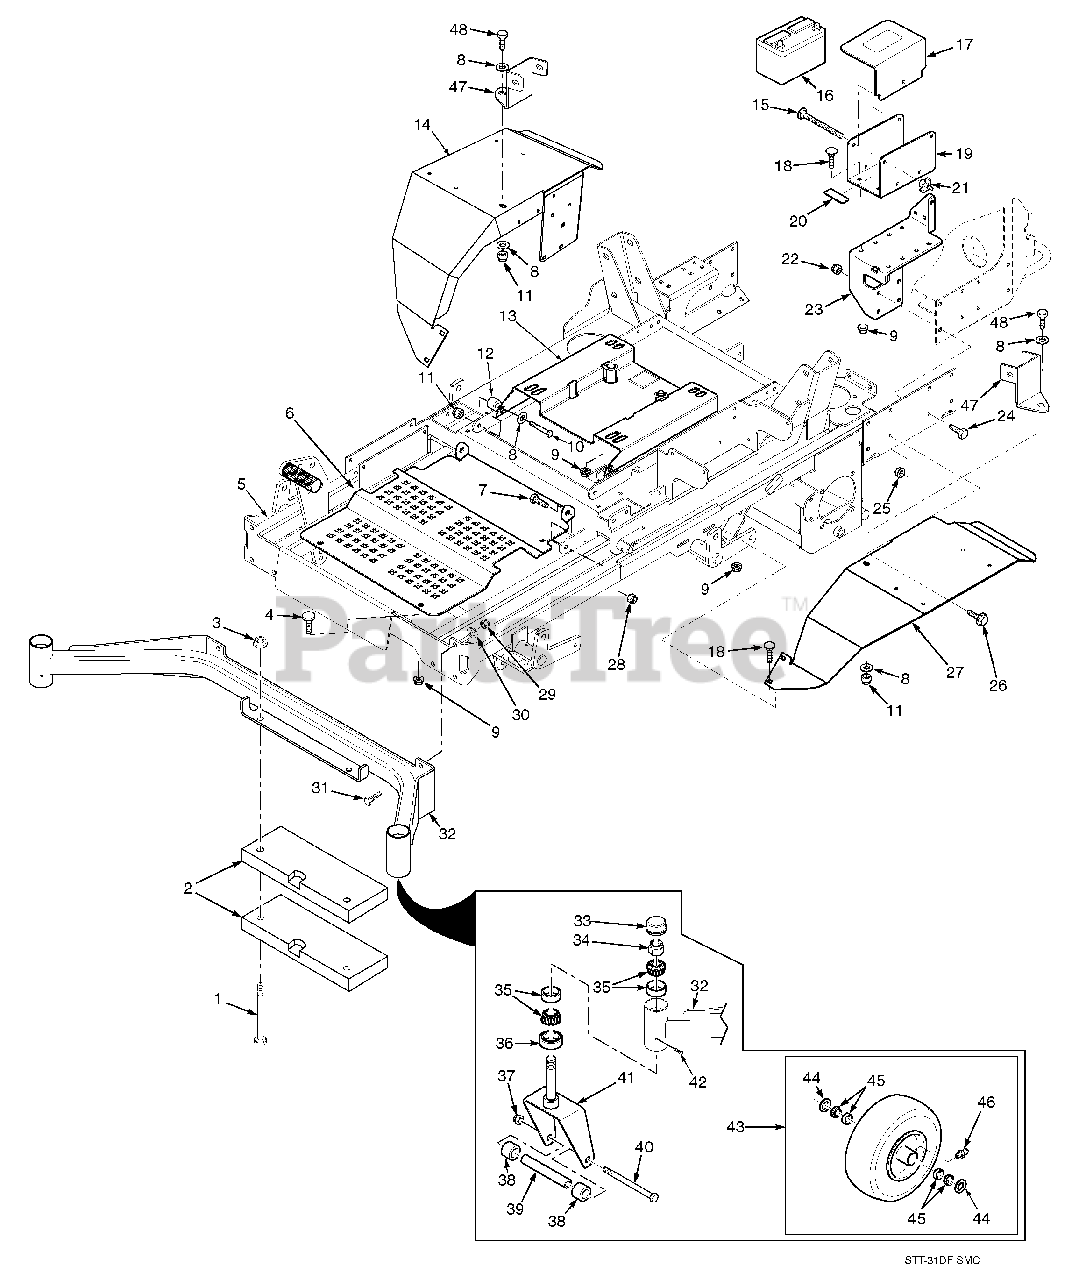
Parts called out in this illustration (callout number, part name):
1	Bolt, Hex Head 1/2-13 x 3.5"
2	Weight
3	Nut, Hex Elastic Stop 1/2-13
4	Bumper, Rubber 5/16-18 x 5/8"
5	Main Frame Assembly w/Decals
6	Foot Plate
7	Bolt, Hex Head 3/8-16 x 1"
8	Flatwasher, 3/8-.391 x .938 x .105
9	Nut, Hex Serrated Flange 5/16-18
10	Bolt, Hex Head 3/8-16 x 2.0"
11	Nut, Elastic Stop 3/8-16
12	Spacer Bushing
13	Seat Plate Weldment w/Decal
14	Fender Weldment, RH
15	Bolt, Carriage 1/4-20 x 6"
16	Battery
17	Cover, Battery
18	Bolt, Carriage 5/16-18 x 3/4"
19	Plate, Battery Box
20	Rubber Pad
21	Wing Nut, 1/4-20 x 3/4"
22	Nut, Elastic Stop 3/8-16
23	Battery Box Mount
24	Bolt, Hex Head 3/8-16 x 1"
25	Nut, Hex Serrated Flange 3/8-16
26	Screw, Hex Serrated Flange 3/8-16 x 1"
27	Fender Weldment, LH
28	Nut, Hex Elastic Stop 3/8-16
29	Nut, Elastic Stop 7/16-14
30	Lockwasher, 7/16"
31	Bolt, Hex Head 7/16-14 x 1-1/4"
32	Extention Weldment, Caster
33	Cap, Grease
34	Nut, Hex Elastic Stop 1.0"-14
35	Bearing W/Race
36	Seal, 2.00" OD. x 1.625" Bore
37	Nut, Hex Elastic Stop 1/2-13
38	Spacer, Caster Wheel
39	Sleeve, Caster Wheel (61V)
40	Bolt, Hex Head 1/2-13 x 9-1/2" (61V)
41	Yoke Weldment, Caster (61V )
42	Plug, 1/4-28 THD Form
43	Wheel Assembly,
45	Bearing w/ Race
46	Grease Fitting
47	Bracket, Fender Support
48	Bolt, Hex Head 3/8-16 x 1-1/4"
